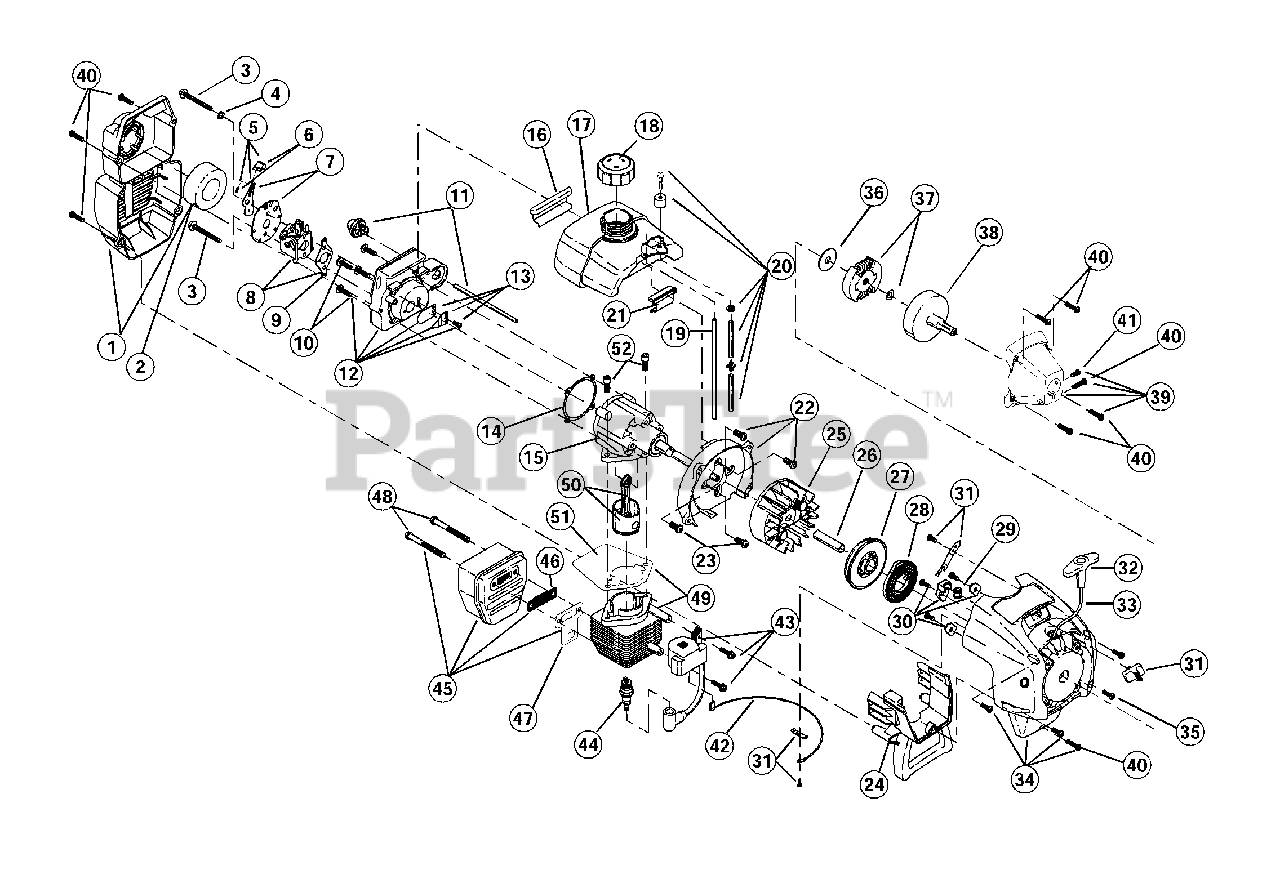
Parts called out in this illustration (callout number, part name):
1	Air Cleaner/Muffler Cover Assembly
2	Air Cleaner Filter
3	Carburetor Mounting Screw Assembly
4	Wavey Washer
5	Choke Lever Assembly
6	Choke Knob and Screw
7	Choke Lever and Plate
8	Carburetor Assembly
9	Carburetor Gasket
10	Carb Mount Screw
11	Primer and Hose Assembly
12	Carb Mount Assembly
13	Reed Assembly
14	Carburetor Mount Gasket
15	Crank Case Service Assembly
16	Rear Mounting Pad
17	Fuel Tank Assembly
18	Fuel Cap Assembly
19	Fuel Return Line
20	Fuel Line Assembly
21	Front Mounting Pad
22	Shroud Assembly
23	Shroud Screw
24	Shroud Extension & Stand
25	Flywheel Assembly
27	Recoil Pulley Assembly
28	Recoil Spring
29	Rope Guide
30	Pulley Retainer Assembly
31	Switch Assembly
32	Pull Handle
34	Starter Housing Assembly
35	Housing Screw
36	Clutch Washer
37	Clutch Rotor Assembly
38	Clutch Drum Assembly
39	Clutch Cover Assembly
40	Cover Screw
41	Anti-Rotation Screw
42	Wire Lead
43	Module Assembly
44	Spark Plug
45	Muffler Assembly
46	Spark Arrestor Screen
47	Exhaust Gasket
48	Muffler Mounting Bolt Assembly
49	Cylinder Assembly
50	Piston and Rod Assembly
51	Cylinder Gasket
52	Cylinder Bolt
